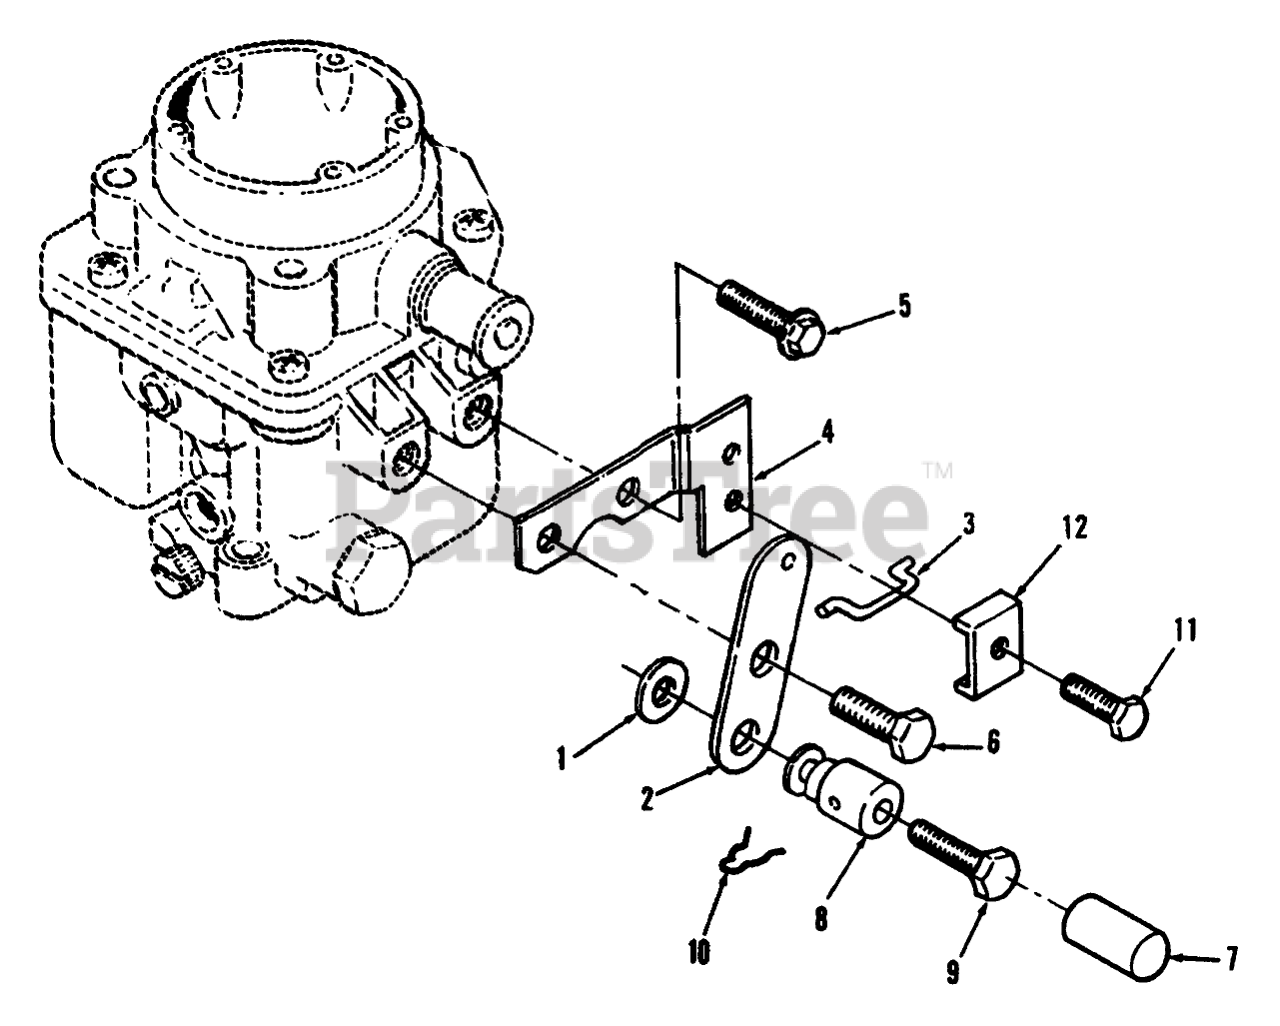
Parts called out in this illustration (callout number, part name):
1	Washer
2	SWIVEL-CHOKE
3	LINK-CHOKE
4	BRACKET
5	SCREW-HWH
6	MACHINE SCREW
7	PLUG
8	SWIVEL
9	SCREW
10	PIN-COTTER
11	SCREW-TAPPING
12	CLIP
